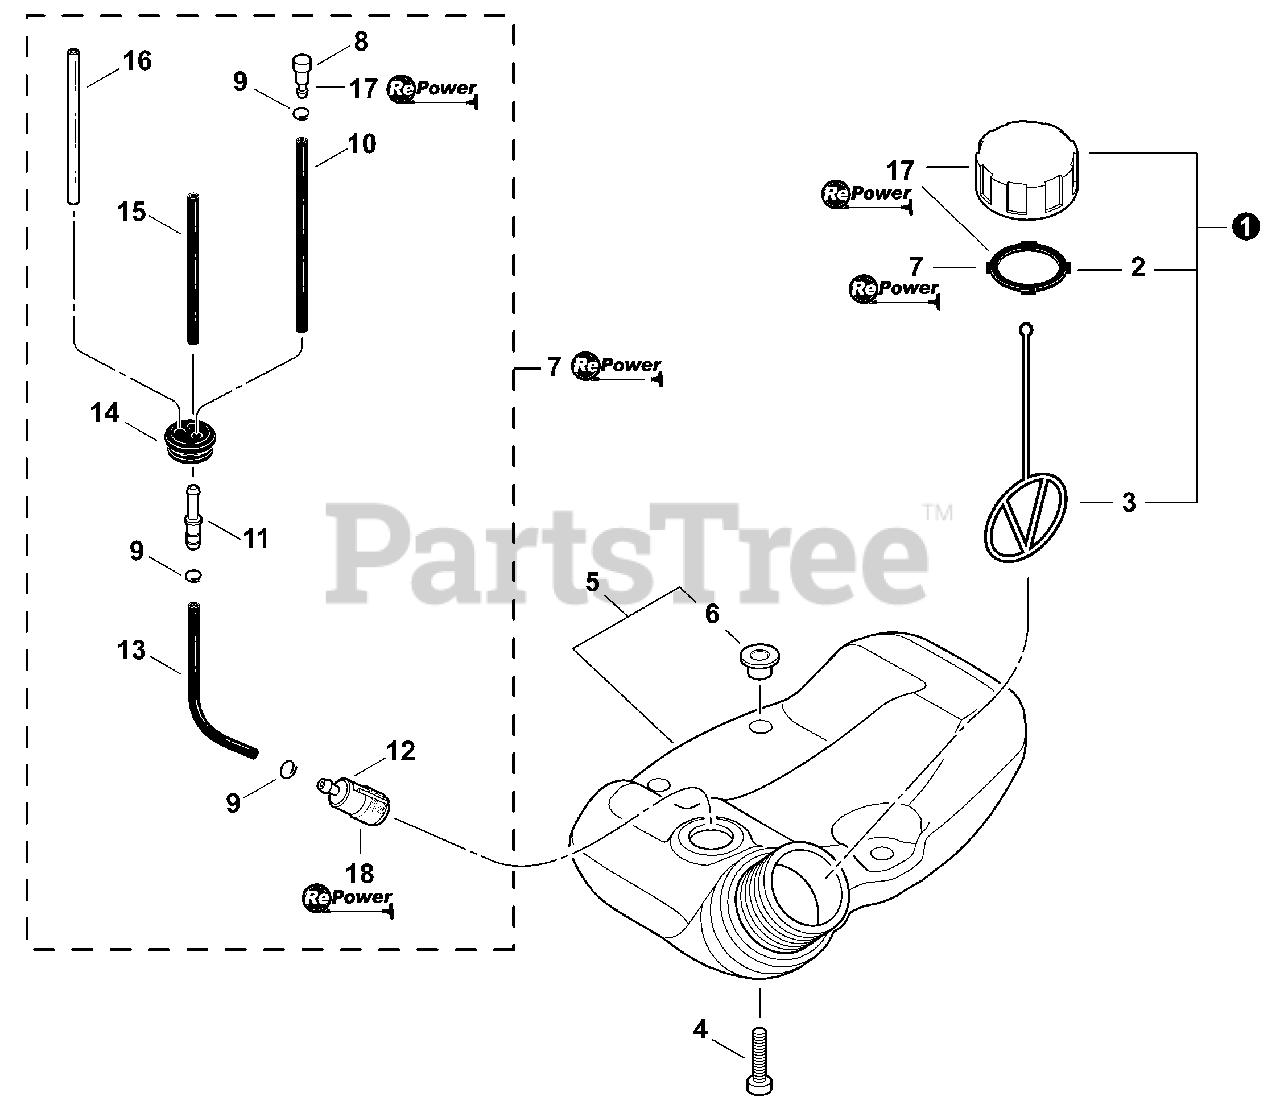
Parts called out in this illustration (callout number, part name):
1	CAP ASSY
2	GASKET, CAP
3	CONNECTOR, CAP
4	SCREW - 5×20
5	FUEL TANK ASSY
7	RePower FUEL SYSTEM KIT
8	VENT, FUEL TANK
9	CLIP - 6
10	PIPE - 3×5×90 -- BLACK
11	CONNECTOR, FUEL PIPE
12	FILTER, FUEL
13	PIPE - 3×5×130 -- BLACK
15	PIPE - 3×5×74 -- BLACK
16	PIPE - 3×6×80 -- CLEAR
17	RePower CAP AND VENT KIT
18	RePower TUNE UP KIT
